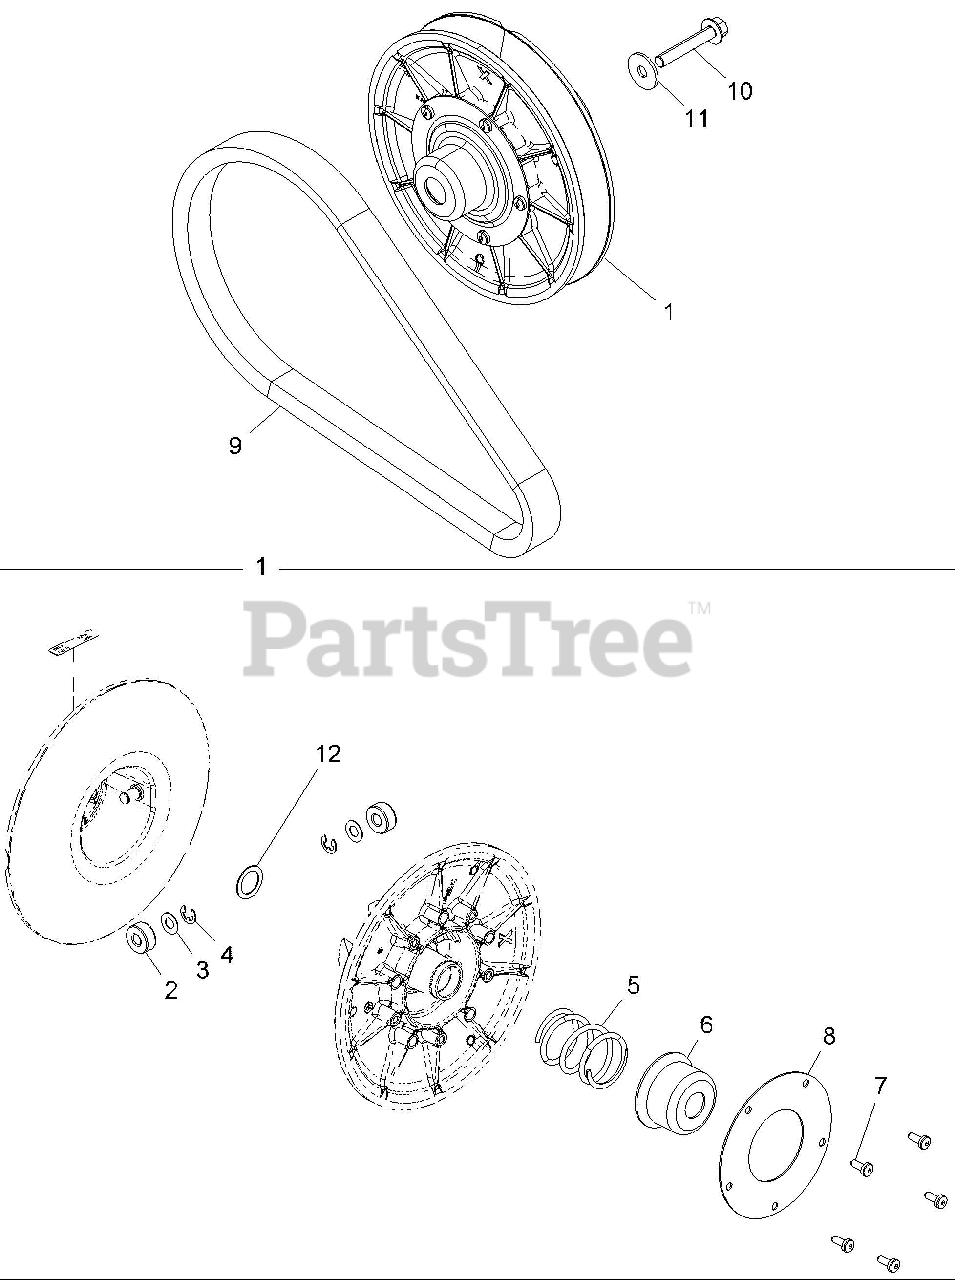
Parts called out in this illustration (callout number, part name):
1	ASM-CLTCH,DRVN,DSL
2	ROLLER-CLUTCH,.955 ODX.450
3	WASHER-THRUST
4	RET.E-RING-E T.375
5	SPRING-CLUTCH,BLW,101-144
6	CUP-SPRING,BOSS LW UTILITY
7	SCR-TORX,M6X1.0X16
8	PLATE,RETAINER,FLAT,BOSS,LW
9	BELT-DRIVE,11"CD
10	BOLT-M10X1.25X60,HXFLG-OLIVE D
11	WASHER, FLAT
12	WSHR-THRUST,1.189X0.838X0.12
12	WASHER
